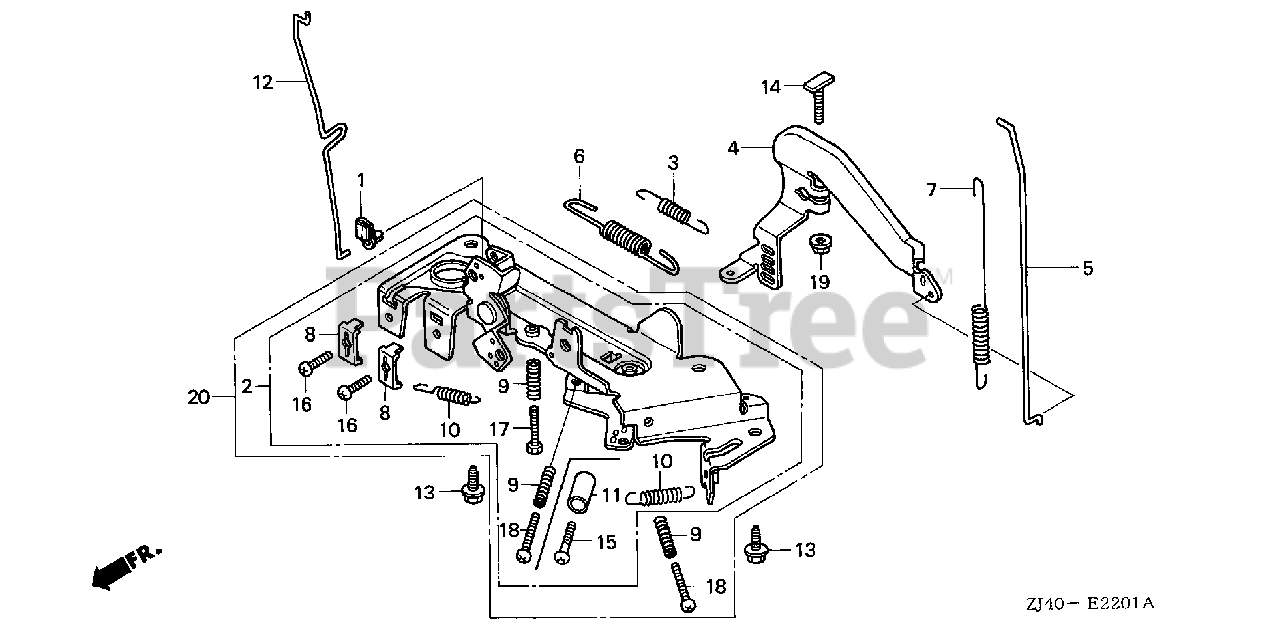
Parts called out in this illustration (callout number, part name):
1	JOINT, ROD
2	CONTROL ASSY.
3	SPRING, STARTER
4	ARM, GOVERNOR
5	ROD, GOVERNOR
6	SPRING, GOVERNOR
7	SPRING, THROTTLE RETURN
8	HOLDER, CABLE
9	SPRING, CONTROL ADJUSTING
10	SPRING, CABLE RETURN
11	COLLAR, STOPPER
12	ROD, CHOKE CONTROL
13	BOLT, FLANGE (6X14) (CT200)
14	BOLT, GOVERNOR ARM
15	SCREW, RECESSED (5X28) (BLACK)
16	BOLT, RECESSED (5X16)
17	BOLT, RECESSED (5X25)
19	NUT, FLANGE (6MM)
